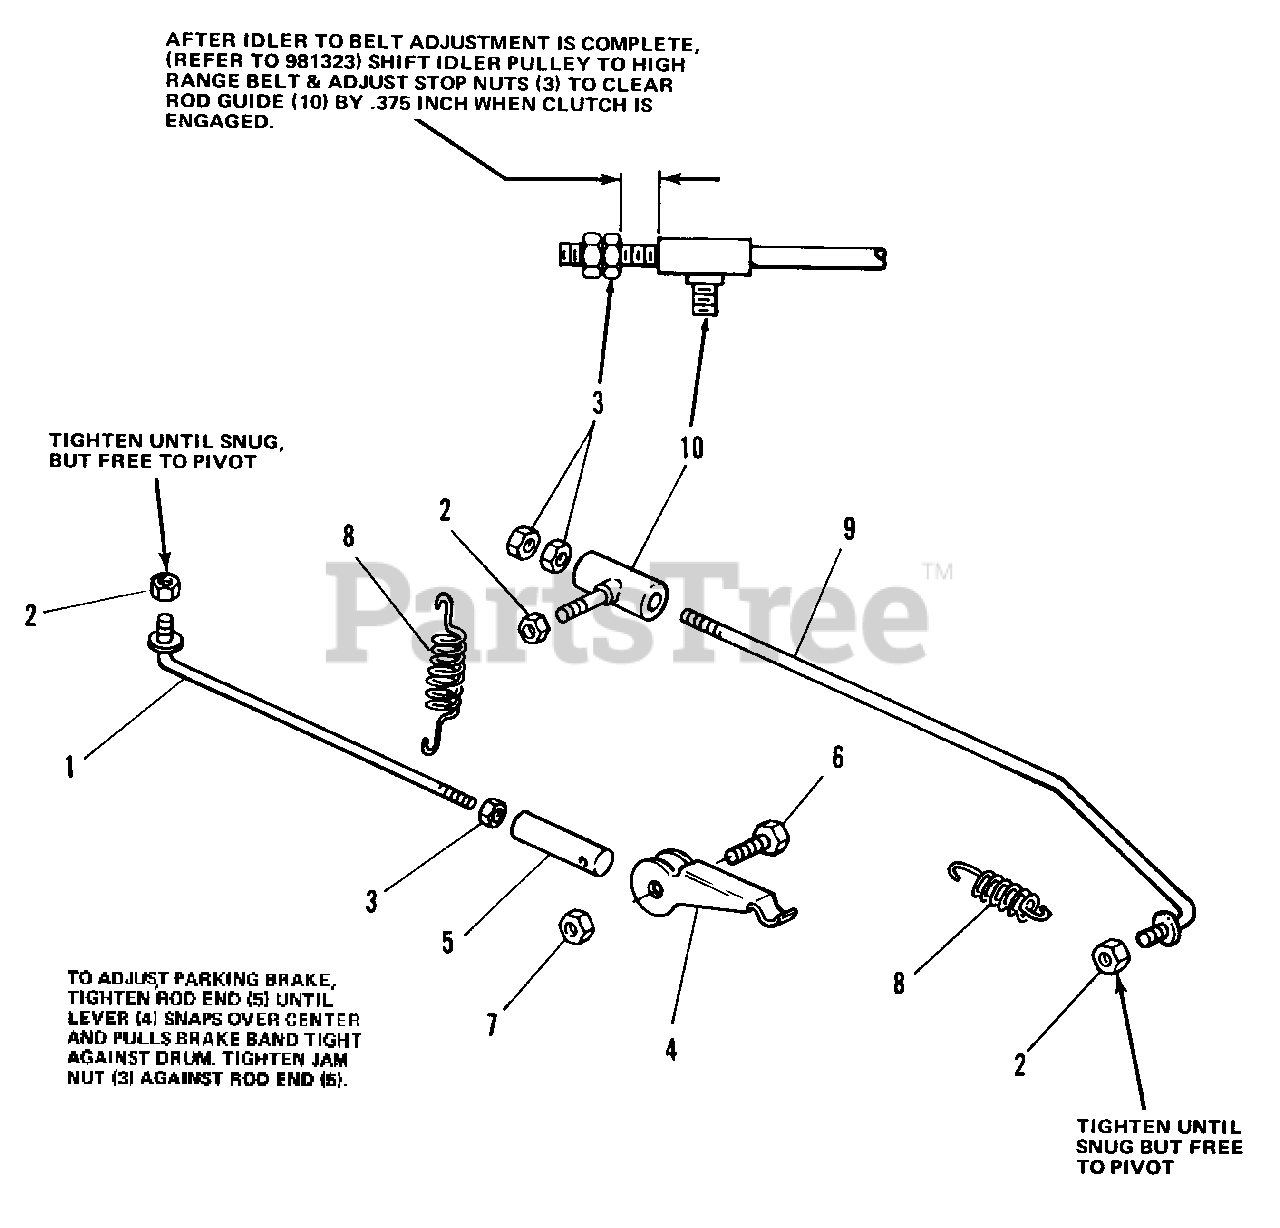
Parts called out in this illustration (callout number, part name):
1	PARKING BRAKE ROD ASSEMBLY
2	LOCKNUT, Hex, .312-18
3	NUT, Hex, Full, .312-18
4	LEVER, Parking Brake
6	CAPSCREW, Hex Hd., .250-20 x 1.25
7	LOCKNUT, Hex, .250-20
9	CLUTCH & BRAKE ROD ASSEMBLY
10	ROD GUIDE ASSEMBLY
